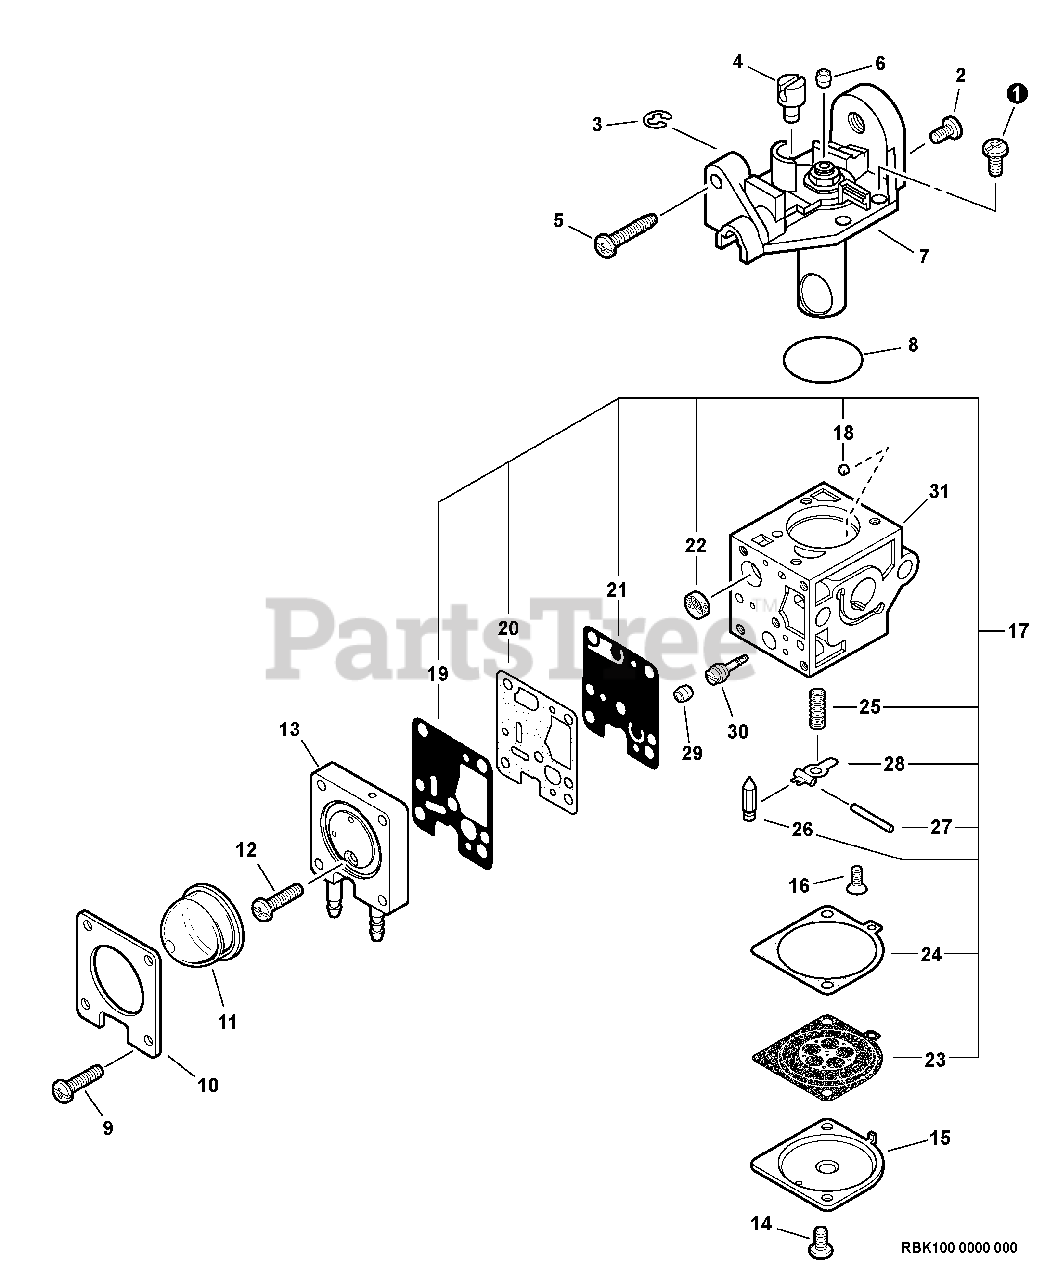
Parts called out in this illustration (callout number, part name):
5	SCREW, THROTTLE ADJUST
7	COVER ASSY, ROTOR
10	RETAINER, PURGE BULB
11	BULB, PURGE
13	BODY ASSY, PURGE
15	COVER, METERING DIAPHRAGM
17	REPAIR KIT, CARBURETOR
18	GUIDE, ROLLER
19	DIAPHRAGM, PUMP
20	GASKET, PUMP
21	DIAPHRAGM, PUMP
22	STRAINER
23	DIAPHRAGM, METERING
24	GASKET, METERING
25	SPRING, METERING LEVER
26	VALVE, INLET NEEDLE
27	PIN, METERING LEVER
28	LEVER, METERING
30	NEEDLE, HIGH SPEED
31	BODY, CARBURETOR
